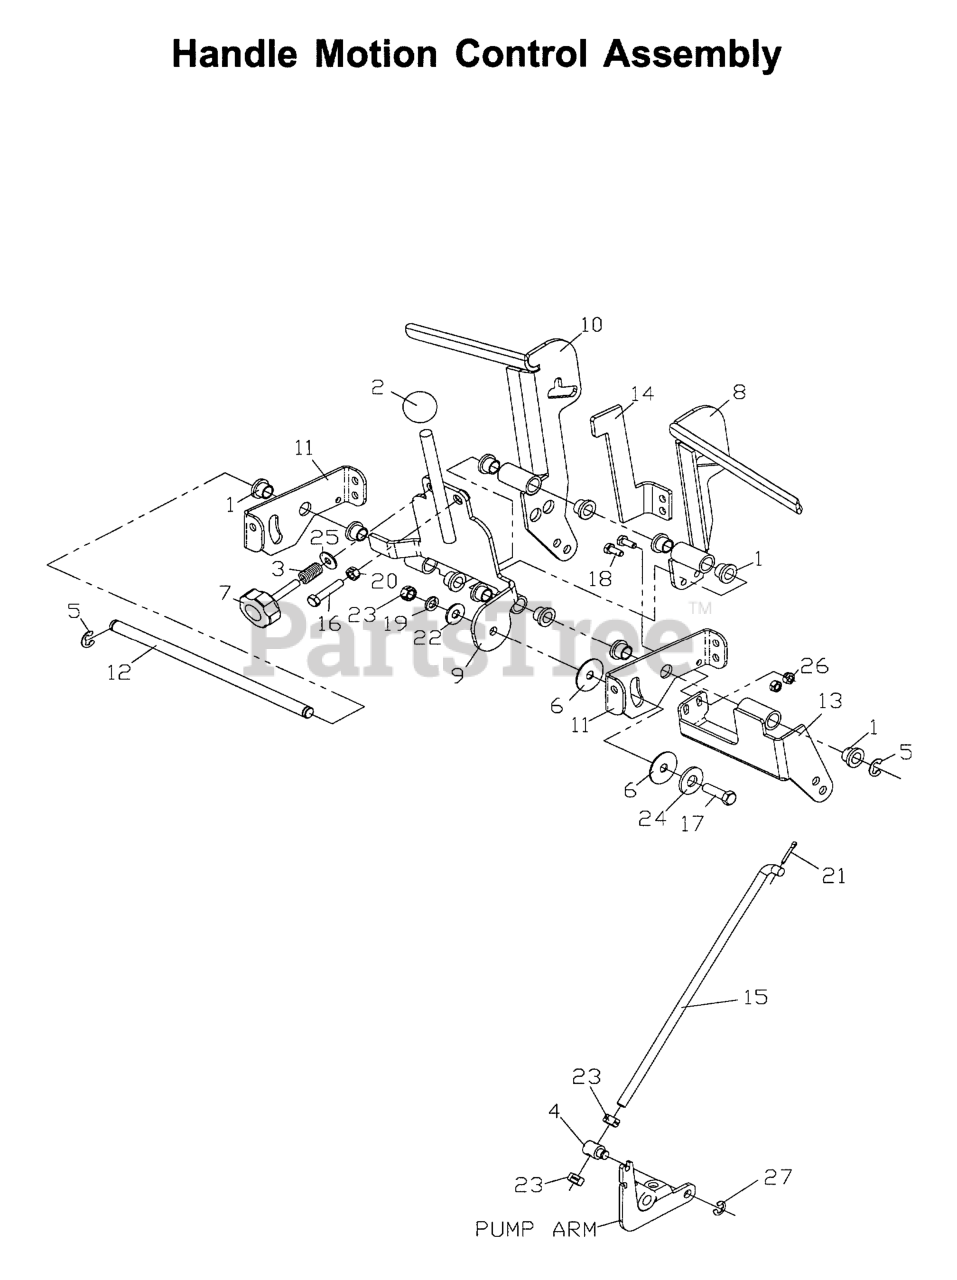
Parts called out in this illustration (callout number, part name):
1	BUSHING, FLANGED NYLON
5	E-RING 1/2 (2 2)
6	WASHER, FRICTION
7	ADJUSTMENT KNOB
8	PADDLE - LH
9	NEUTRAL BAR
10	PADDLE - RH
11	CROSS BRACE
14	STOP PLATE
15	DRIVE LINKAGE
16	CAPSCREW 5/16 X 1/1/2 HEX HEAD
17	HCS 3/8C X 1 1/4 GR5
18	HCS 1/4C X 5/8
19	SLW 3/8 STD
20	NUT 5/16C CENTERLOCK
21	RP_COTTER PIN 1/8 X 3/4
22	WASHER 3/8 FLAT
23	NUT 3/8C CENTERBLOCK
24	WASHER 1/2 FLAT
25	WASHER 5/16 FLAT
26	NUT 1/4C CENTER LOCK
27	E RING 3/8"
